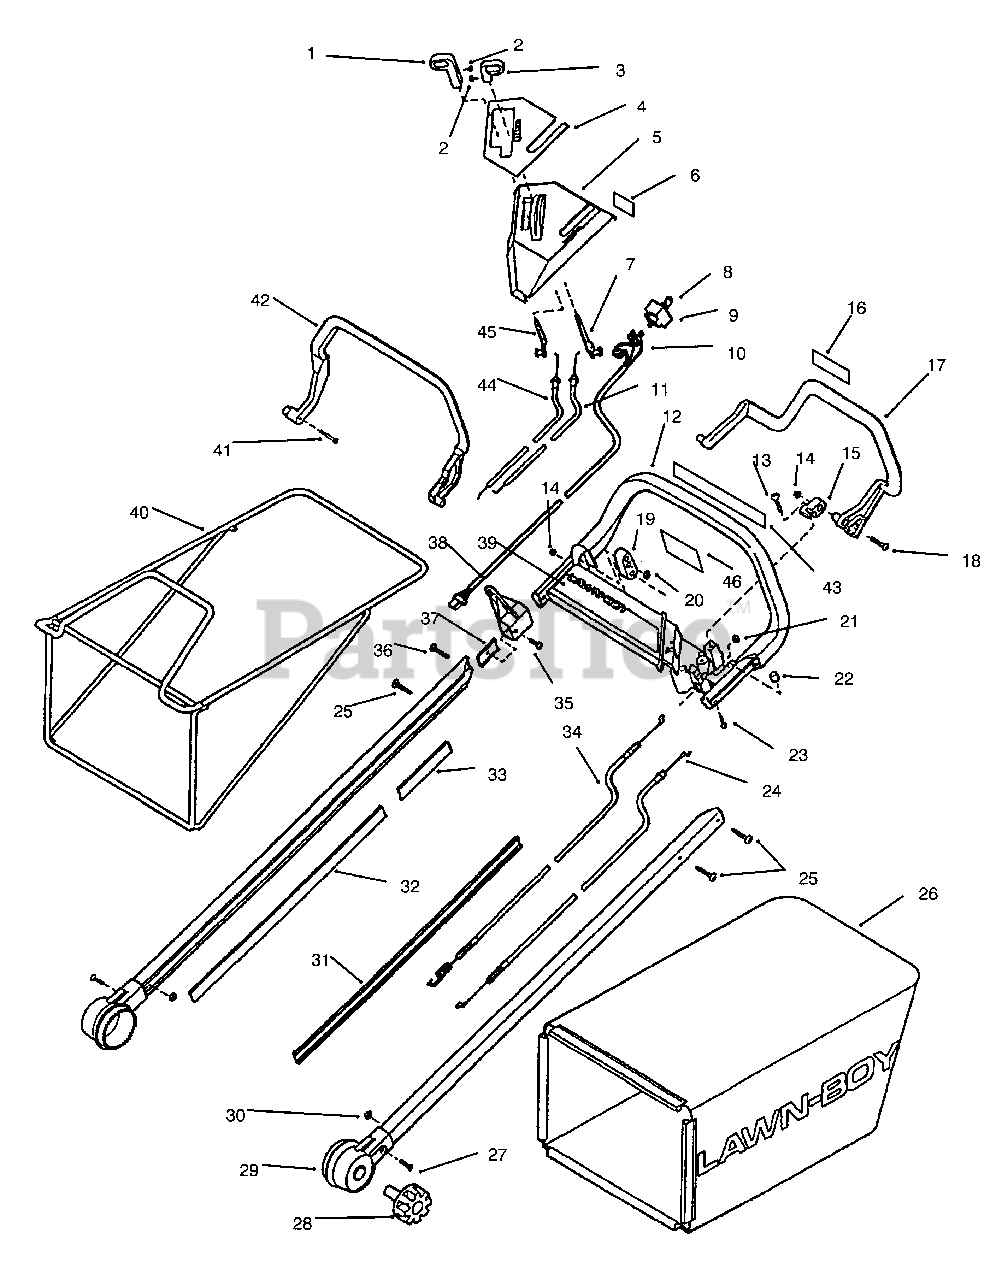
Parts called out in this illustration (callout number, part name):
1	Assy.-Knob, Gear Select (Incl. Ref. #2)
2	Screw-Set
3	Assembly-Knob, Throttle (Incl. Ref. #2)
5	Assembly-Cover, Upper (Incl. Ref. #4)
6	Decal-Electric Start
7	Lever-Throttle
8	Key-Ignition
9	Assembly-Switch
10	Wire Harness
11	Assembly-Cable, Throttle
12	Assy.-Handle & Decal
15	Pivot-Bail
16	Decal-Self Propelled
17	Bail-Self-propelled
19	Block-Bail
21	Nut-Cable, Self-propelled
24	Assy.-Cable, Eng. Brake
25	Screw-Thread Forming
28	Knob-Mounting, Handle
29	Knuckle-Handle (Incl. Ref. #27 & 30)
31	Insert-Handle, Cable Side
32	Insert-Handle
33	Insert-Handle
34	Assy.-Cable, Self-propelled
37	Plate-Nut
38	Guide-Rope
39	Decal-Lawn-Boy
42	Bail-Brake, Engine
43	Decal-Zone
44	Assy.-Cable, Gear Select
45	Lever-Gear Select
46	Decal-Warning
